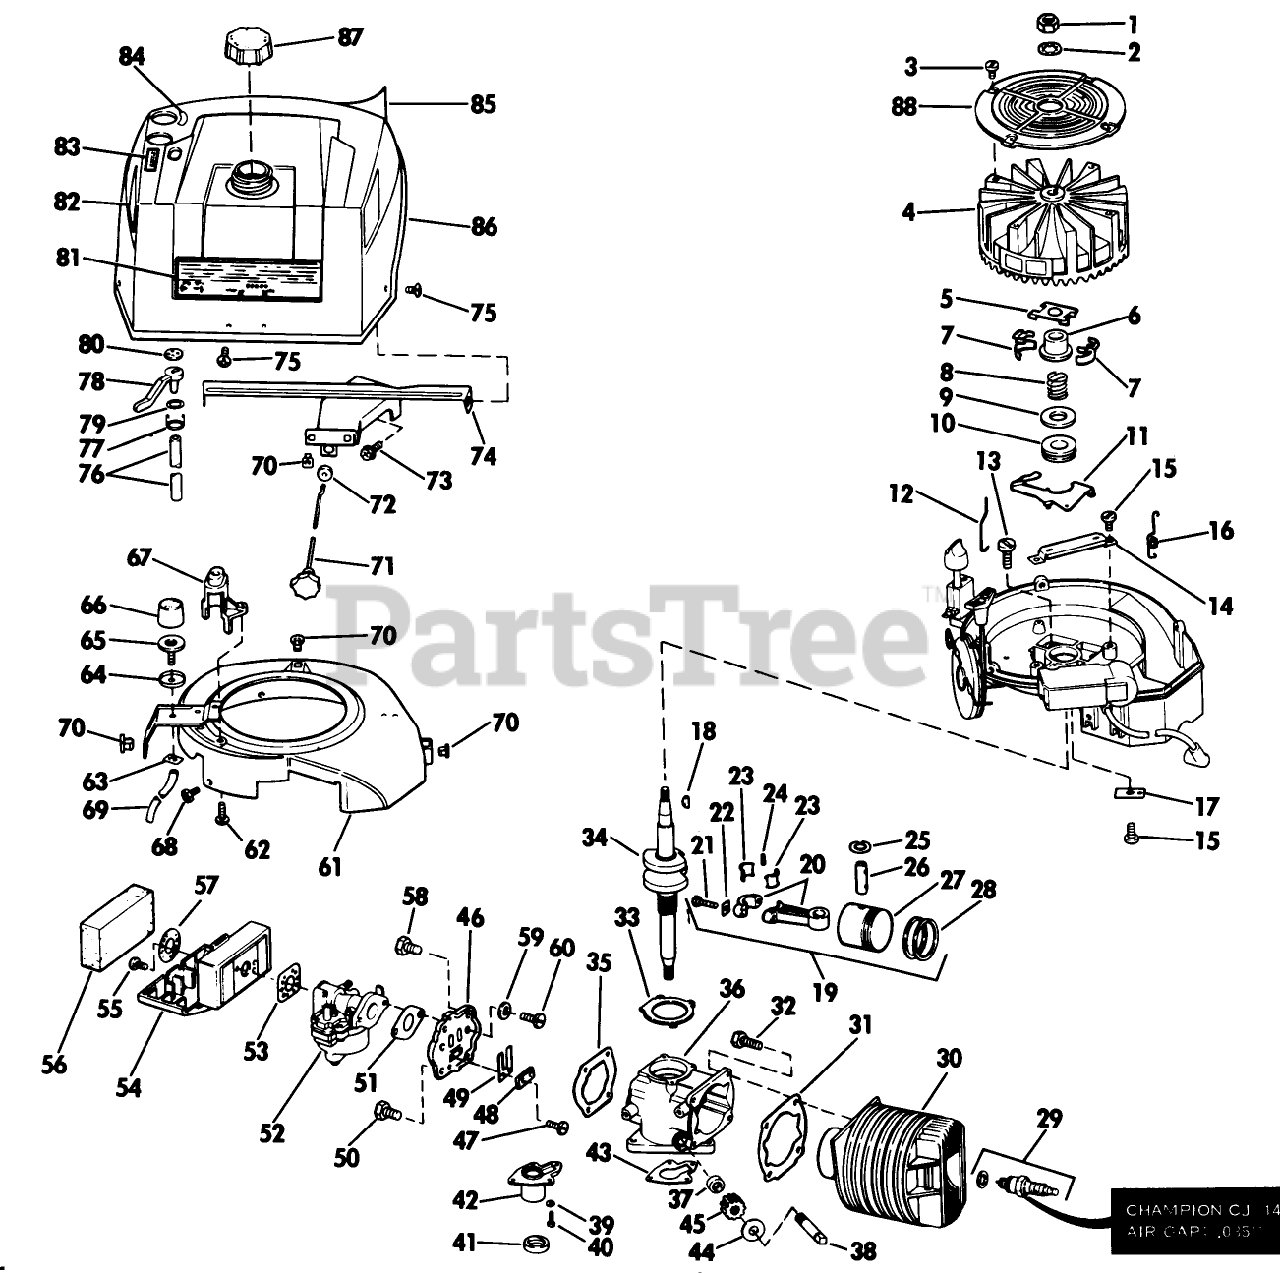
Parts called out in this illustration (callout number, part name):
3	SCREW F
6	COLLAR S
8	SPRING S
11	LEVER-GOVERNOR S
14	BRACKET
15	SCREW S
23	LINER ASM
25	RING-RETAINING
29	Spark Plug
31	GASKET S
33	GASKET S
35	GASKET S
43	GASKET-CVR S
44	THRUST WASHER
46	REED PLATE AY. S
48	PLATE-BACKUP, REED
50	SCREW S
51	GASKET S
53	GASKET S
55	SCREW S
56	AIR FILTER S
57	WASHER S
58	SCREW S
63	LOCKNUT S
64	CUP-BULB
70	NUT-CLIP
73	SCREW S
74	BRACKET
75	SCREW S
79	WASHER S
